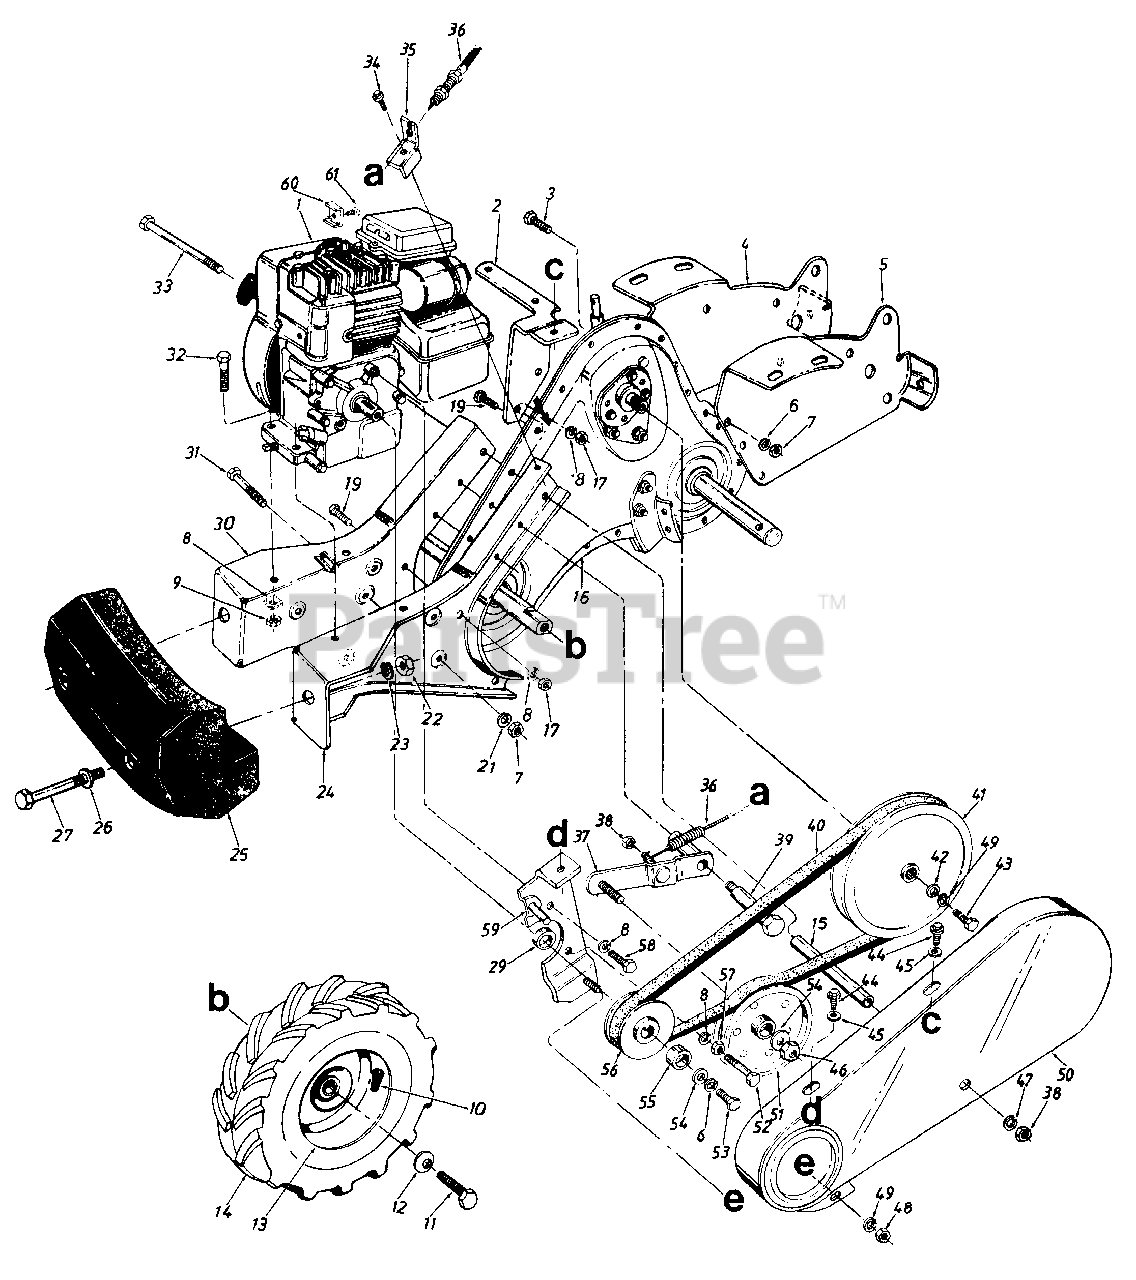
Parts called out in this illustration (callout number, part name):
1	Engine
2	Belt Cover Mounting Brkt.
3	Hex Bolt 3/8-16 x 1.00" Lg.
7	Hex Nut 3/8-16 Thd.
8	L-Wash. 5116 I.D.
9	Hex Nut 5/16-18" Thd.
10	Air Valve
11	Hex Bolt 5/16-24 x .62" Lg.
12	Bell-Wash. .345" I.D. x .88
13	Wheel Rim Ass'y. Only
14	L.H. Wheel Ass'y. Comp.
16	Transmission Comp.
17	Hex Nut 5/16-18 Thd.
19	Hex Bolt 5/16-18 x .75" Lg.
21	L-Wash. 3/8" I.D.H.D.
22	Hex Nut 1/2-13 Thd.
23	L-Wash. 1/2" I.D.
26	Fl-Wash. .510" I.D. x 1.0"
27	Hex Bolt 1/2-13 x 5.00" Lg.
29	Spacer.79" I.D. x 1" O.D.
32	Hex Bolt 5/16-18 x 1.50"
33	Hex Bolt 5/16-18 x 4 75n Lg.Grade 2
34	Hex Wash. TT-Tap Scr. 5/16-18 x .62" Lg.
35	Bracket Clutch Cable
36	Clutch Control Cable 53" Lg.
39	Shld. Bolt .500" Dia. x 2.27"
40	"V"-Belt
41	"V"-Pulley Split 5/8n l.D.
42	Fl-Wash. 1/4" I.D. x .93" O.D.
43	Hex Bolt 1/4-28 x .75" Lg.
44	Hex Wash. Hd. S-Tap Scr. 1/4 -20 x .50" Lg.
45	Fl-Wash. .281" I.D. x .625"
46	Hex Cent. L-Nut 3/8-24 Thd.
47	Fl-Wash. 5/16" I.D.
48	Hex Nut 1/4-20 Thd.
49	L-Wash. 1/4" I.D.
51	Fl-ldler w/Flanges 3.75" O.D.
52	Hex Bolt 5/16-24 x 1.75"
53	Hex Bolt 3/8-24 x 1.00" Lg.
54	Fl-Wash. 3/8" I.D. x 1.00"
55	Spacer.758" I.D. x .990"
56	Engine Pulley
57	Hex Nut 5/16-24 Thd.
58	Hex Bolt 5/16-24 x .62" Lg.
61	Hex Sems Scr. #10-32 x .62"
